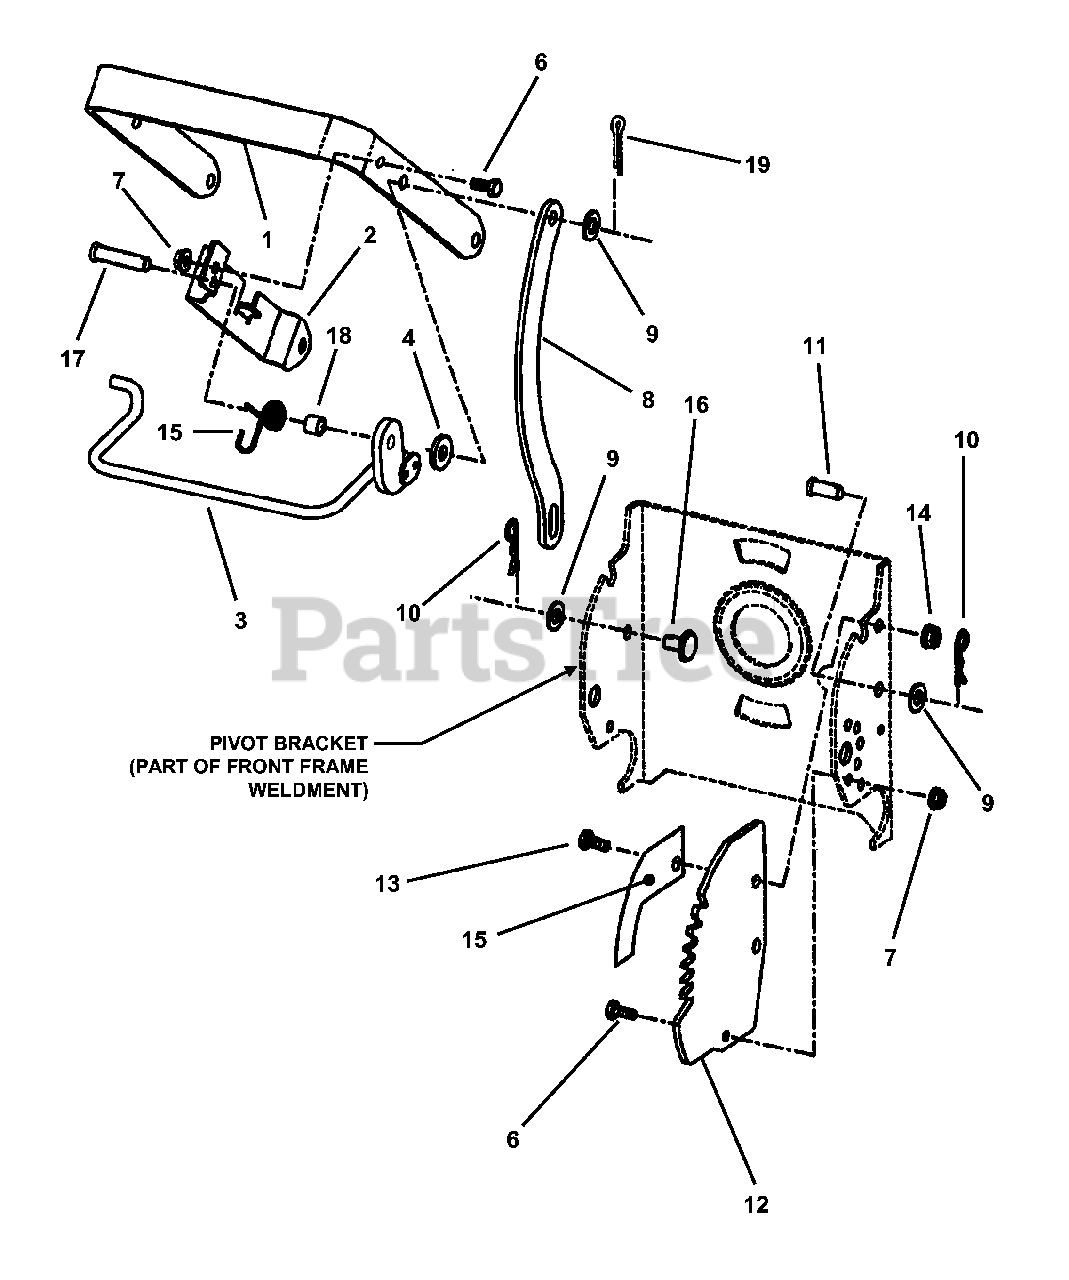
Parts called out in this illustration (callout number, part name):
1	HANDLE, Deck Lift
2	BRACKET, Pivot Support
3	LEVER, Deck Lift/Handle Release
4	WASHER, Slipper
5	SPRING, Torsion (Deck Position)
6	SCREW, 1/4-20 x 5/8" Hex head Cap, Grade 5
7	NUT, 1/4-20 Hex Flange Lock
8	BAR, Deck Lift
9	WASHER, 3/8" Flat
10	HAIRPIN, 3/32 x 1-1/2"
11	PIN, 3/8 x 7/8" Large Head Clevis
12	PLATE, Detent
13	SCREW, 5/16-18 x 3/4" Hex Cap, Grade 5
14	NUT, 5/16-18 Hex Flange Lock, Grade 5
15	DECAL, Deck Position
16	PIN, 3/8 x 1/2" Expanded Head Clevis
17	PIN, 3/8 x 1-5/8" Clevis
19	PIN, 3/32" x 3/4" Cotter
